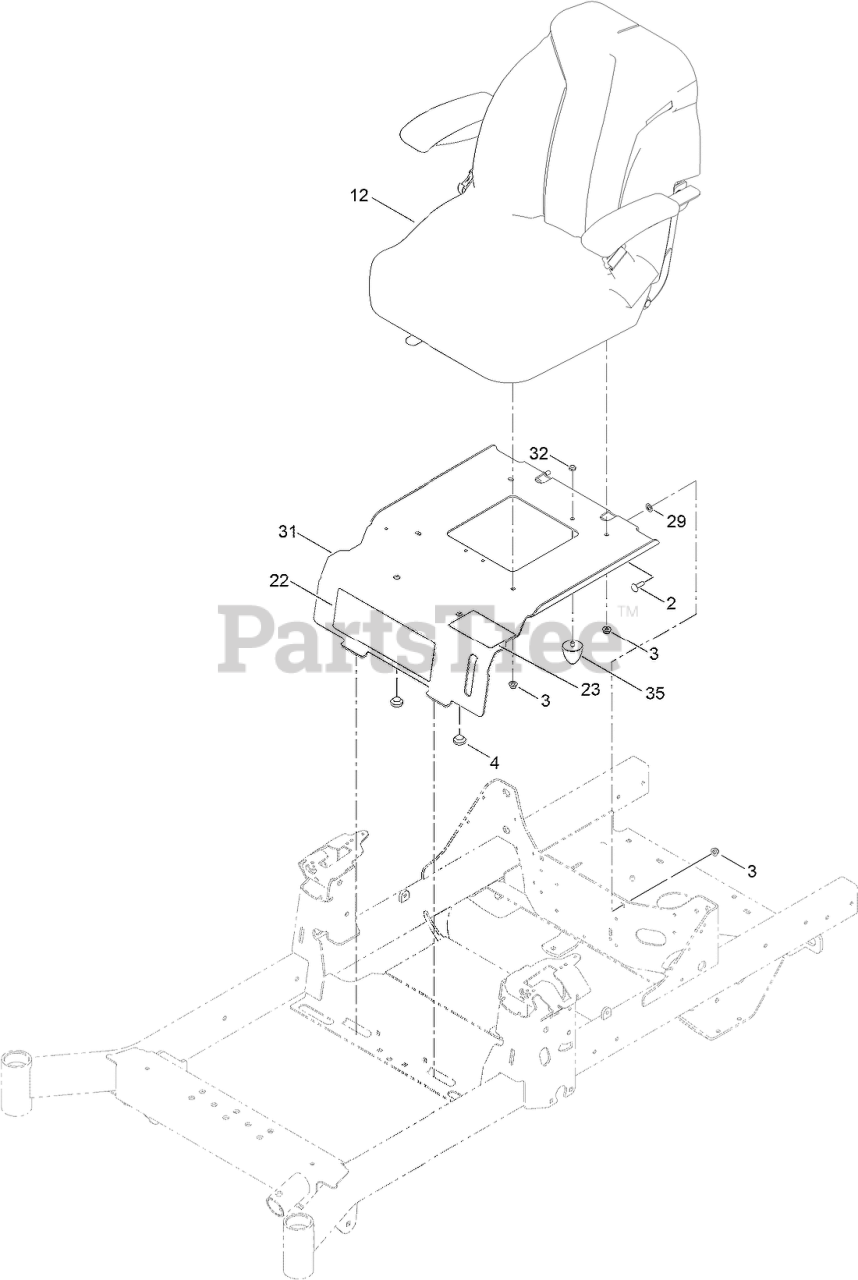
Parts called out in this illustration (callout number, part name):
2	SCREW-CARR
3	NUT-HF, NI
4	BUMPER-SEAT
12	ASM-SEAT TORO
22	DECAL-TITAN MAX
23	DECAL-AID, SERVICE
29	WASHER-RETAINING
31	PLATE-FIXED SEAT
32	NUT-LOCK, NI
35	BUMPER-RUBBER
